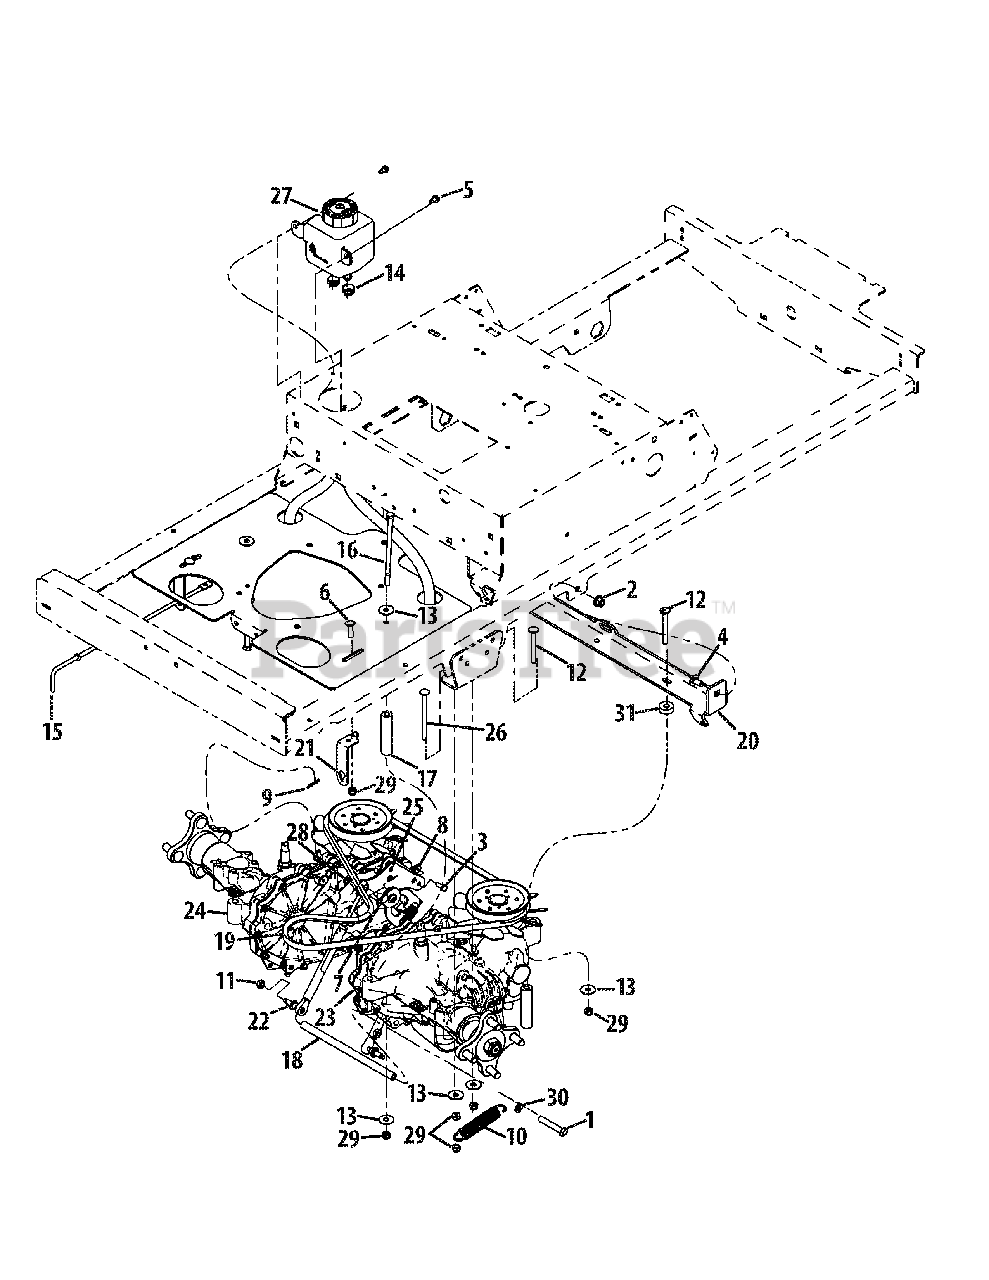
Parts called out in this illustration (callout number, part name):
1	Hex Screw, 3/8-16 x 2.00
2	Flange Counterlock Nut, 3/8-16
3	Hex Screw, 1/4-20 x .620
4	Carriage Bolt, 3/8-16 x .75
5	Hex Flange Screw, 1/4-20 x .500
6	Carriage Bolt, 5/16-18 x 1.00
7	Shoulder Bolt, 1/4-28 x .38 x .465
8	Toplock Flange Nut, 1/4-20
9	Hair-Pin, 1/8 x 1.125 x .072
10	Extension Spring, .865 x 4.7 x .12
11	Nylock Nut, M8-1.25
12	Carriage Bolt, 5/16-18 x 2.75
13	Washer, .313 x 1.06 x .062
14	Hose Clamp, .750
15	Pump Relief Rod
16	Hex Screw, 5/16-18 x 6.00
17	Spacer, .375 x .750 x 3.30
18	Transmission Support Tube
19	V-Belt
20	Front Mount Transmission Bracket
21	Neutral Bracket
23	RH Transmission Assembly
24	LH Transmission Assembly
25	Control Arm Damper Bracket
26	Carriage Bolt, 5/16-18 x 4.0
27	Expansion Tank Assembly
28	Jam Nut, 1/4-28
29	Hex Lock Nut, 5/16-18
30	Lock Washer, 3/8
31	Spacer, .406 x 1.00 x .38
